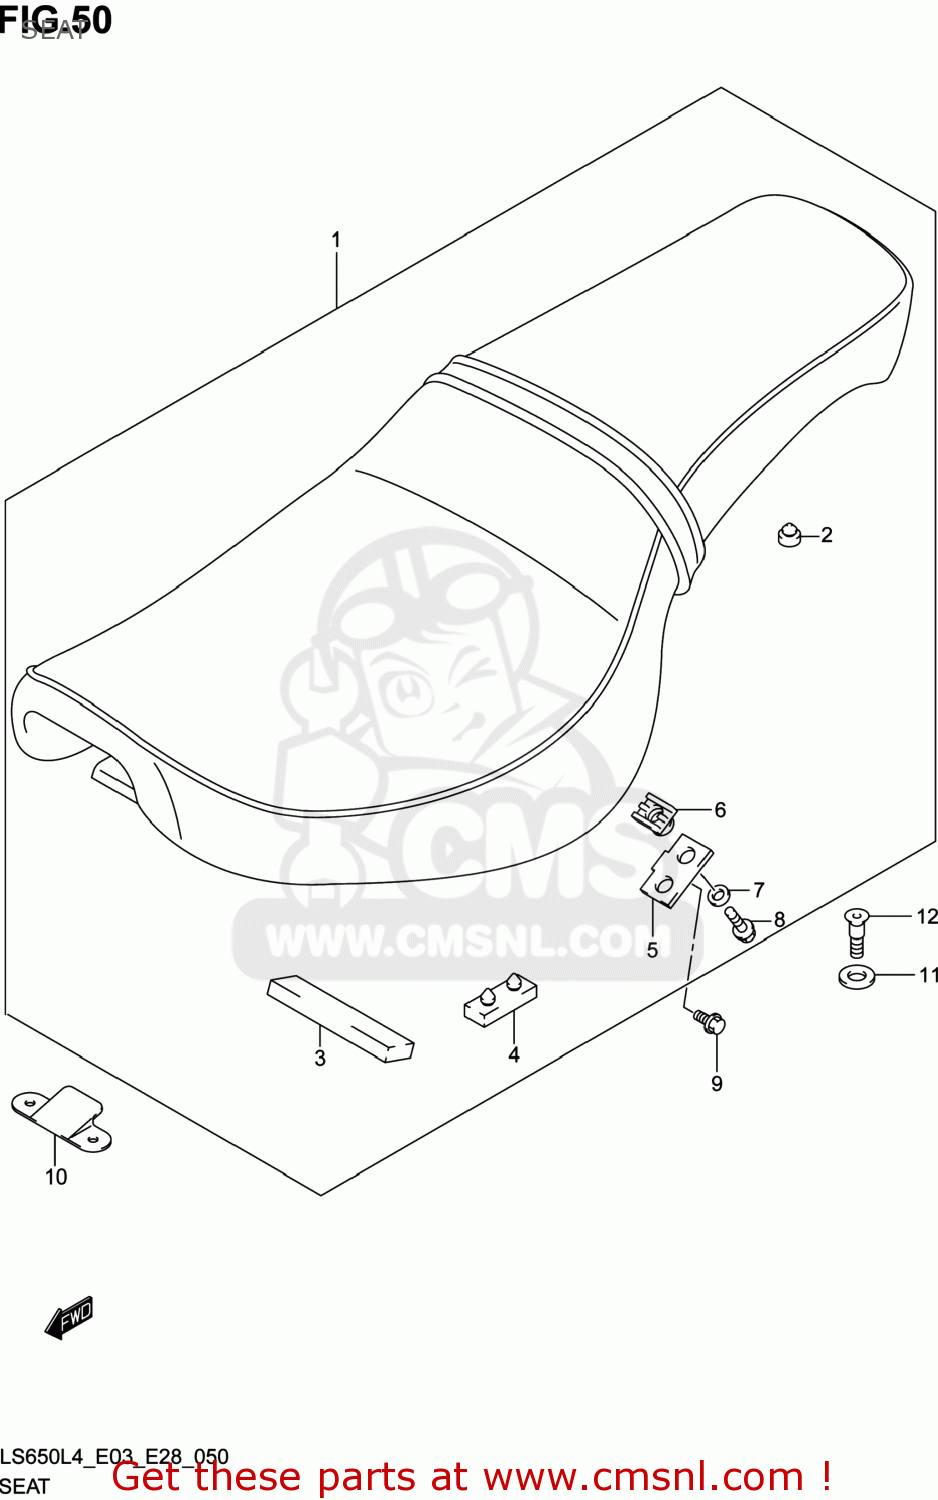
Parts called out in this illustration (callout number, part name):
1	SEAT ASSY
2	CUSHION,SEAT
3	CUSHION,CTR FR
4	CUSHION,SEAT
5	BRACKET,SEAT RR
6	CUSHION,SEAT RR BRACKET
7	WASHER(6.5X20X1.6)
8	BOLT
9	BOLT
10	PLATE,SEAT HOOK FR
11	CUSHION,SEAT RR
12	SCREW(6X12)
